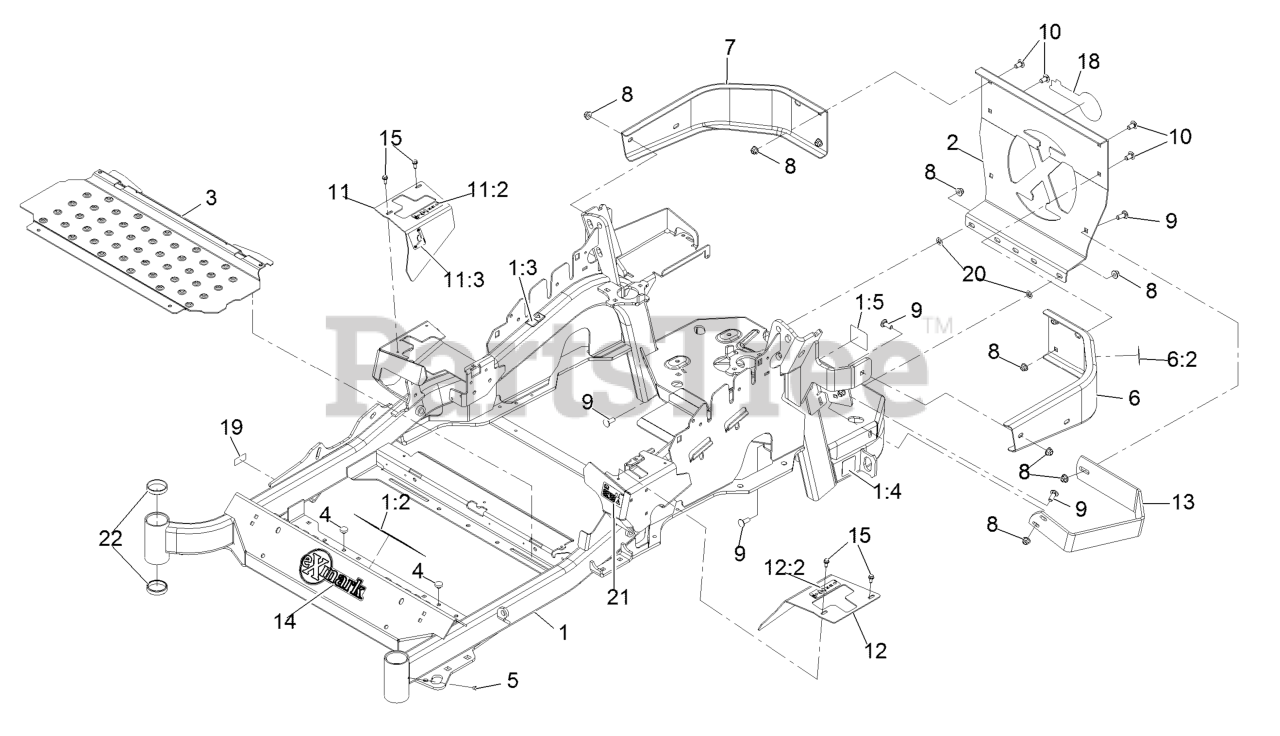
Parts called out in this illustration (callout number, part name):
1	Mainframe ASM
1:2	Decal-Danger
1:3	Decal-Warning
1:4	Decal-Hazard, Pinched Finger
1:5	Decal-Spark Arrester
2	Plate,Rear Guard
6	LH Bumper ASM
6:2	Decal-Warning
7	Bumper-RH
8	Nut-Nyloc 3/8-16 Flg
9	Bolt-Carriage 3/8-16 X 1
10	Bolt-Carriage 3/8-16 X 3/4
11	RH Motion Control Cover ASM
11:2	Decal-Control, Motion
11:3	Decal-Park Brake, CE
12	LH Motion Control Cover ASM
12:2	Decal-Control, Motion
13	Guard-Muffler
14	Decal-Exmark Logo
15	Screw-HWH 1/4-20 X .62
18	Decal-Exmark Logo
19	Decal-Patent
20	Nut-Push 3/8-16
21	Decal-Fuel Fill, CE
22	Cup-Bearing Tapered Roller
